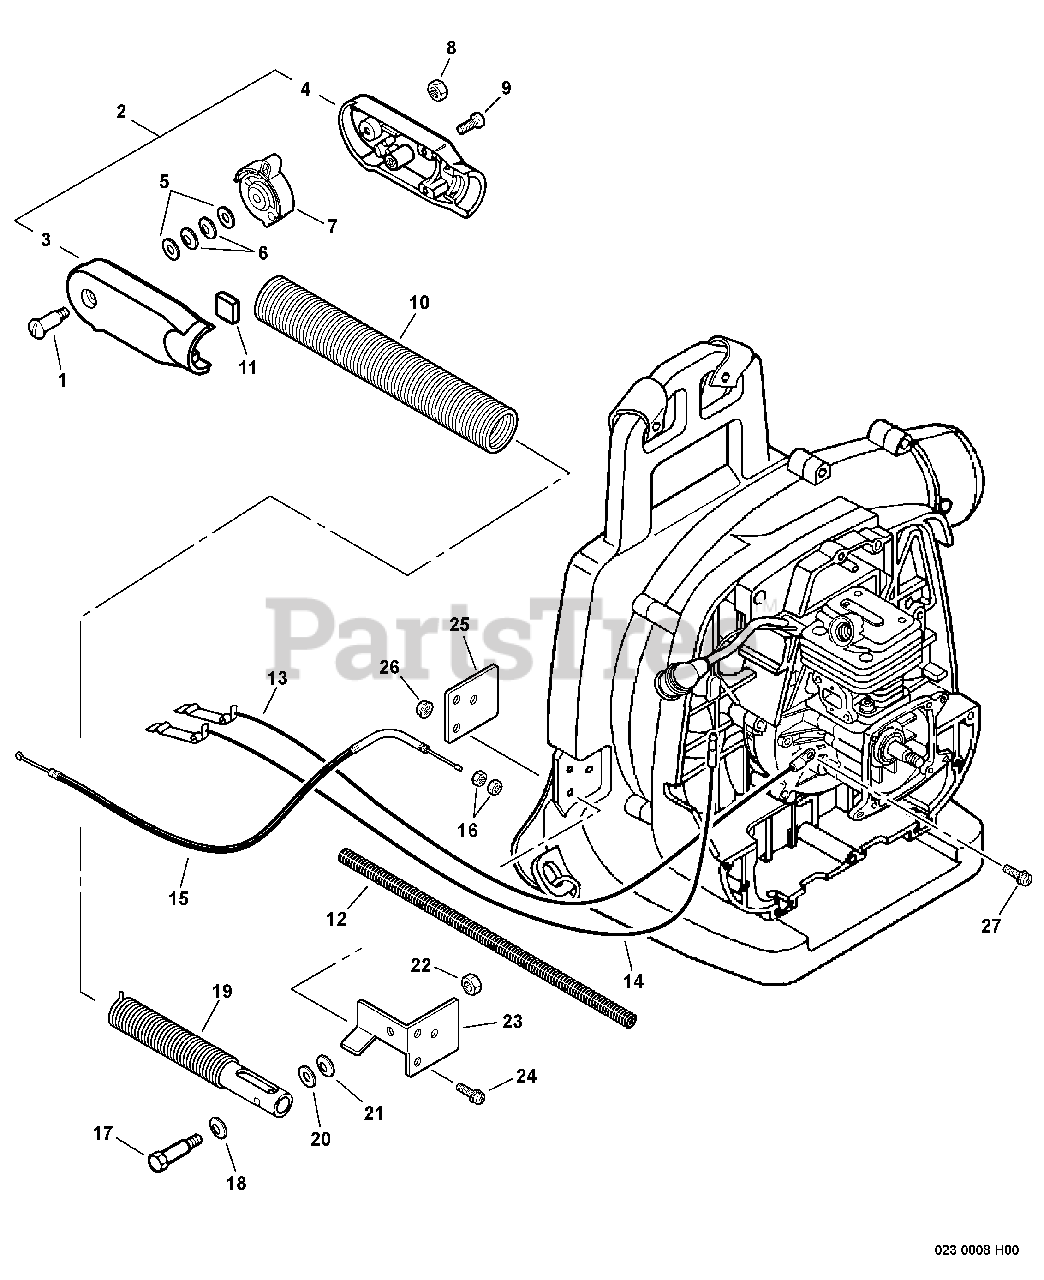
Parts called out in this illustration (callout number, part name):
2	GRIP ASSY, THROTTLE
3	GRIP, LEFT THROTTLE
4	GRIP, RIGHT THROTTLE
5	WASHER 6.5×15.5×0.6
6	WASHER, FRICTION 6.6×14.3
7	LEVER, THROTTLE
8	NUT, LOCK 4
10	TUBE, OUTER FLEX
11	PAD, FOAM
12	TUBE, PROTECTIVE - CORRUGATED
13	LEAD - GROUND
14	LEAD - IGNITION
15	CABLE, THROTTLE
18	WASHER, WAVE
19	TUBE, SPRING
20	WASHER 8
21	WASHER - 8
23	BRACKET, MOUNTING
24	SCREW 5×16
26	NUT, FLANGE M5
27	SCREW 5×10
